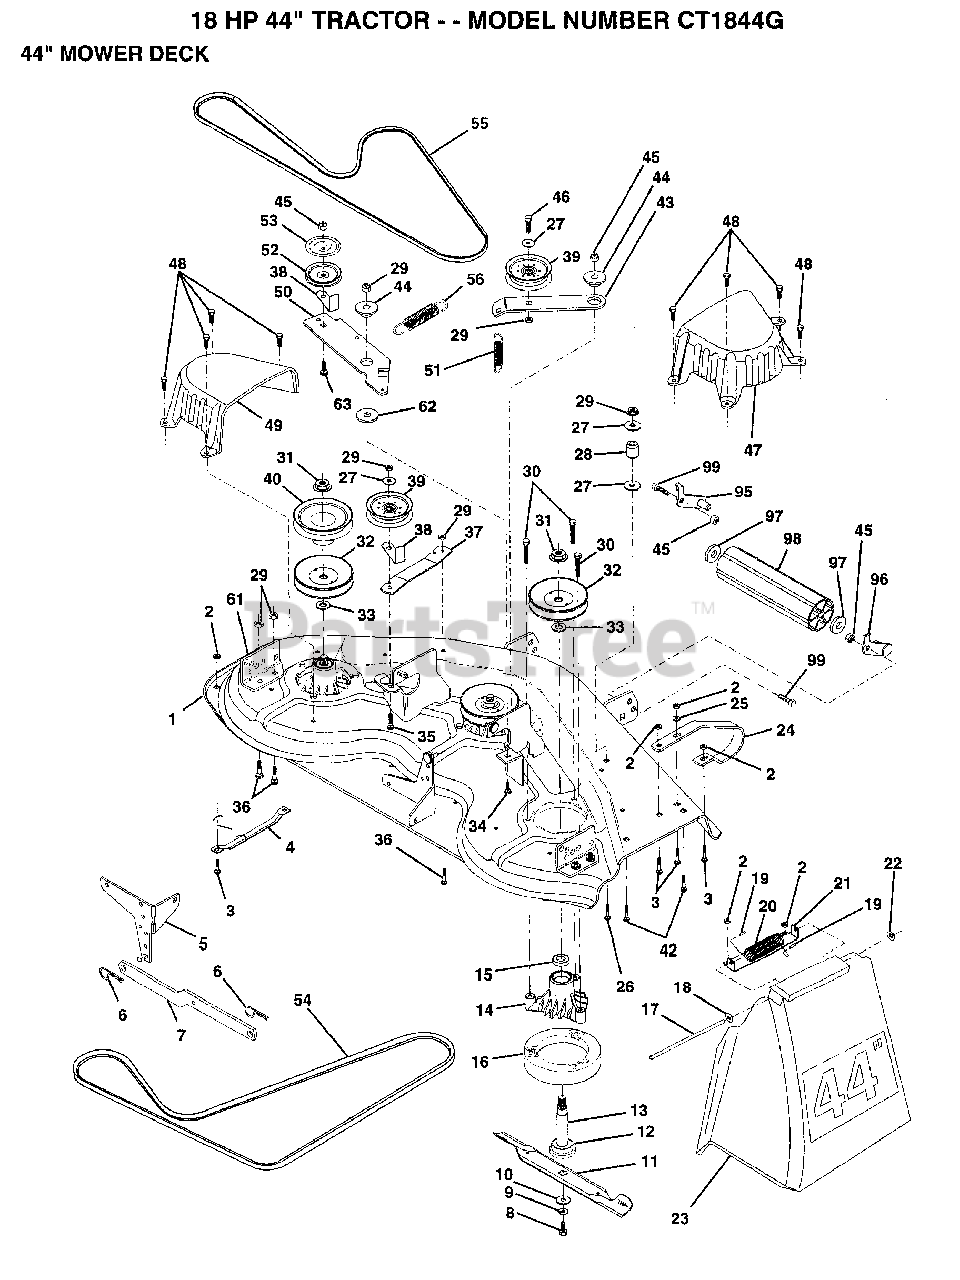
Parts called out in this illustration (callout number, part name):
1	"DECK ASM WELD44"""
2	NUT
4	RUNNER-LH M
5	BRKT.ASM.SW.44/50
8	BLADE BOLT
10	WASHER.HARD.BLADE
11	"BLADE.44"" HIPERF"
12	BEARING.BALL
13	SHAFT.ASM.W/BRNG
14	HOUSING.MAND.44.V
15	BEARING
17	ROD-HINGE T
18	WASHER
19	CAP-SLEEVE LT
20	SPRING TORSION
21	BRKT DEFLECTOR
22	NUT PUSH M
23	DEFLECTOR SHIELD
24	RUNNER.RH
25	WASHER M
26	BOLT
27	WASHER
29	NUT
33	WASHER
34	BOLT.3/8-14X1.25
35	BOLT
36	BOLT D
37	STIFFENER.ARM.IDL
39	FLAT IDLER PULLEY
40	"PULLEY.DRIVEN.44"""
42	BOLT
43	"ARM.IDLER.SEC.44"""
44	SPACER RETAINER
47	"COVER.MAND.RH.44"""
48	SCREW.1/4-20X5/8
49	COVER.MANDREL.LH
50	ARM.IDLER.PRIMARY
51	"SPRING.SEC.44""VEN"
52	PULLEY.IDLER.VGRO
53	SHIELD.IDLER.44.V
54	V-BELT.PRIM.78.5.
55	BELT-V.88.12.MW
56	SPRING.EXT.DECK.
61	BRACKET.GUAGE.WHL
62	HARDENED WASHER
63	BOLT.3/8-16X1.50
97	WASHER
99	BOLT
